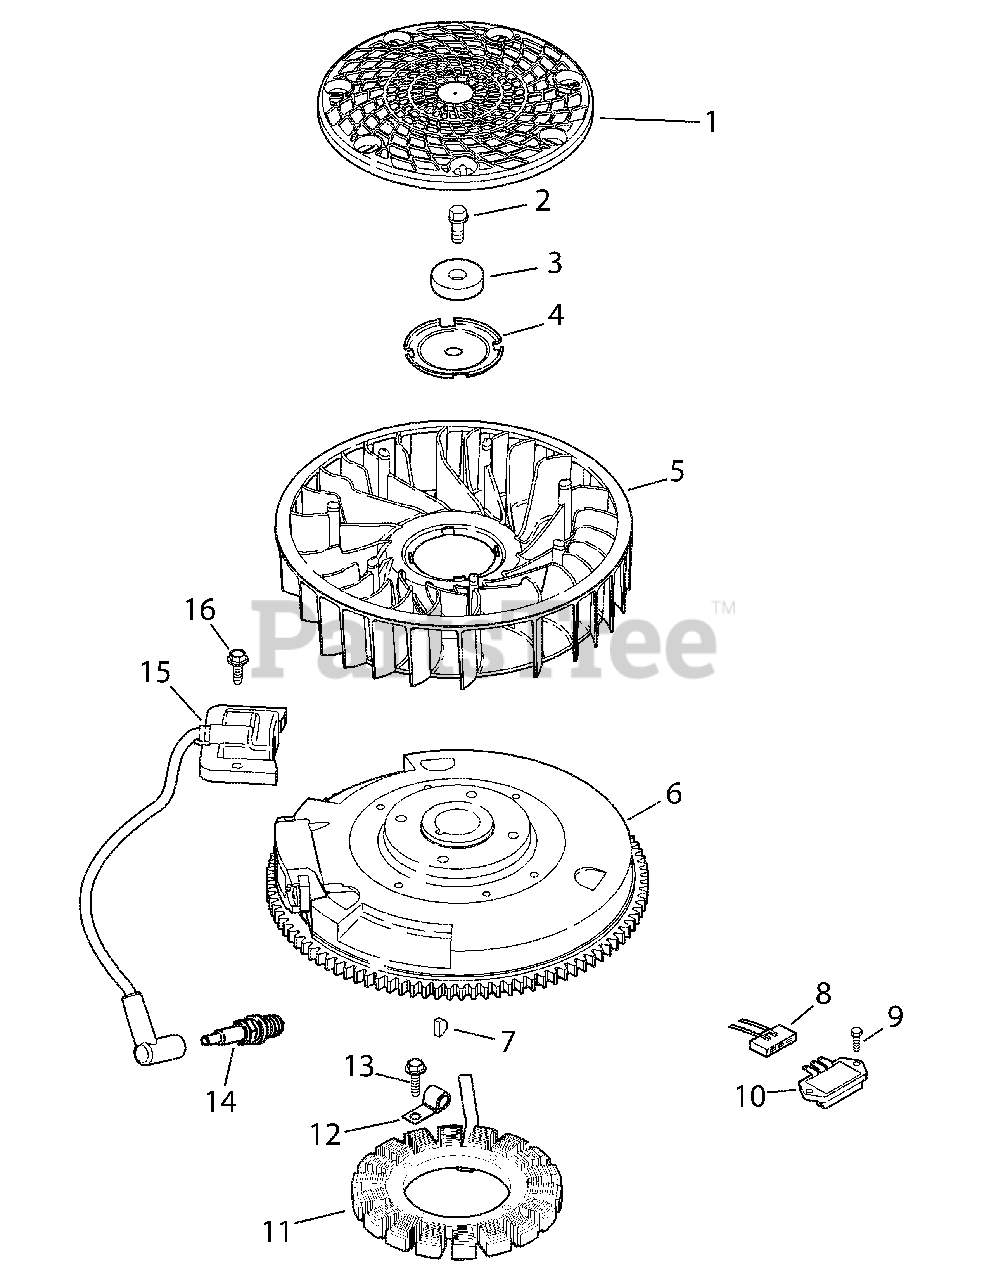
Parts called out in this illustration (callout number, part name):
1	Screen, grass
2	Screw, hex. flange M10x1.5x45
3	Washer, plain 3/8"
4	Plate, fan mounting
5	Fan
6	Flywheel
8	Connector (3 contact)
9	Screw, heavy hex. flange M5x0.8x16
10	Rectifier-regulator
11	Kit, 15 amp stator
12	Clip, cable
13	Screw, hex. head thread forming
14	Spark plug
15	Module, ignition
16	Screw, hex. flange thread forming
